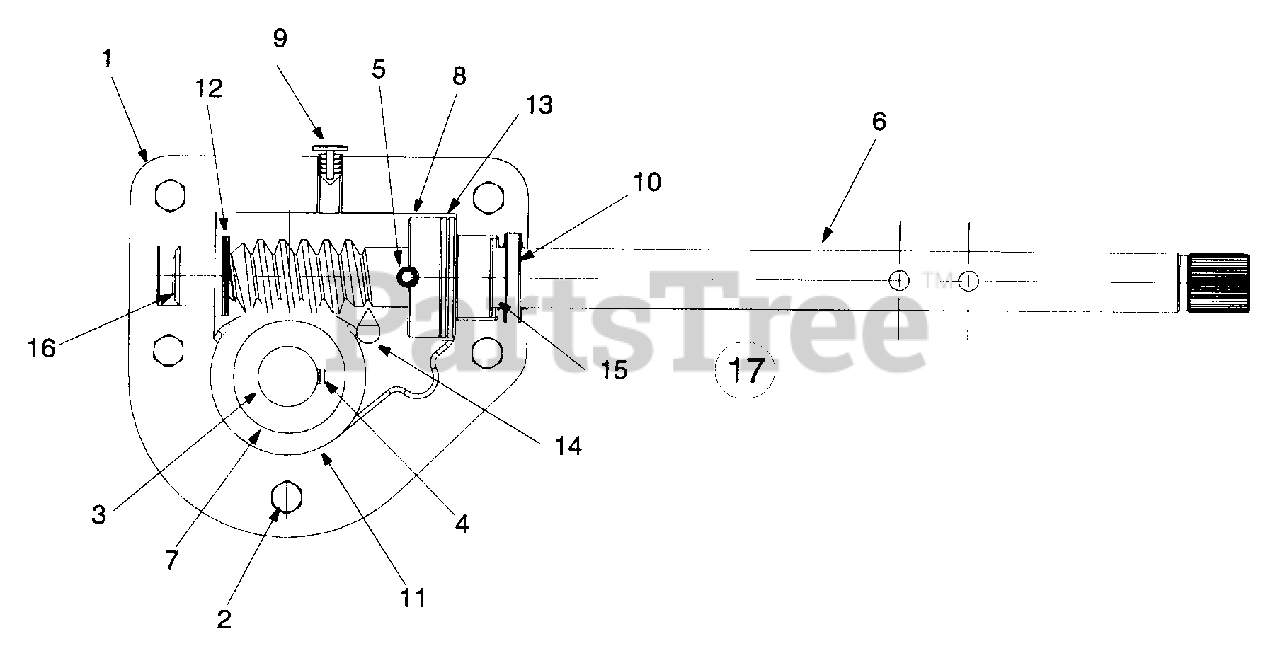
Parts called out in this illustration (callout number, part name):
1	Housing - L.H.
2	Hex Screw 1/4-20 x .75
3	Spiral Axle 24"
4	Key
5	Pin-Spiral
6	Shaft-Worm
7	Gear-Worm
8	Collar-Thrust
10	Seal-Oil
11	Washer-Flat
12	Washer-Flat
13	Washer-Flat
14	Grease
15	Bearing-Flange
16	Bearing-Flange
17	Ass'y. Complete 24"
